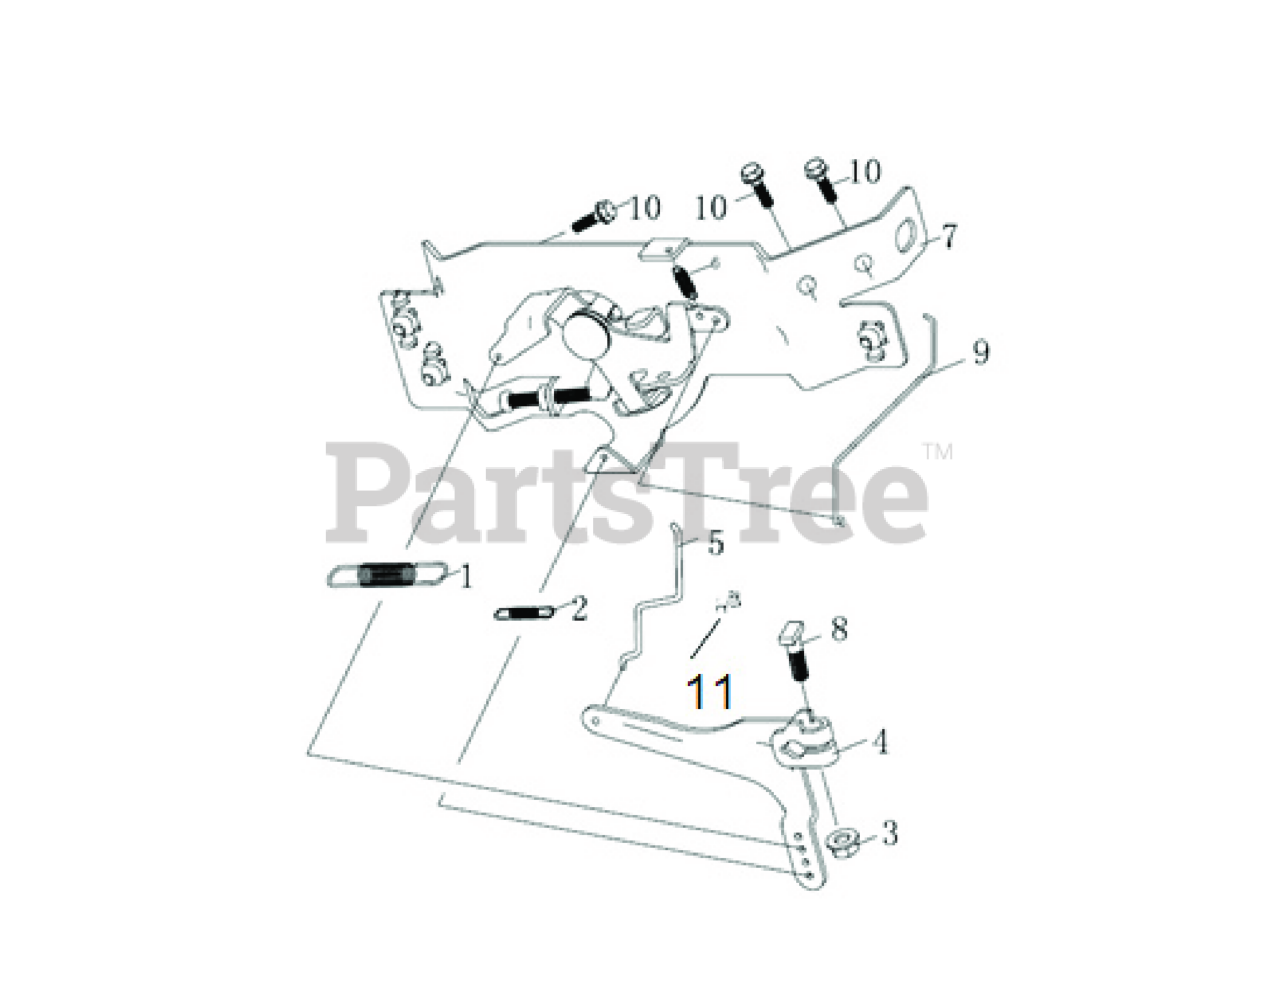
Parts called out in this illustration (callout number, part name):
1	Spring, Governor, SR708
2	Spring, Throttle Return
3	Nut, Flange
4	Bracket, Speed Regulating
5	Linkage, Throttle
6	Spring, Throttle Return
7	Bracket, Throttle Assembly
8	Set Screw
9	Linkage, Choke
10	Bolt, Flange
11	Bracket, Throttle Control
